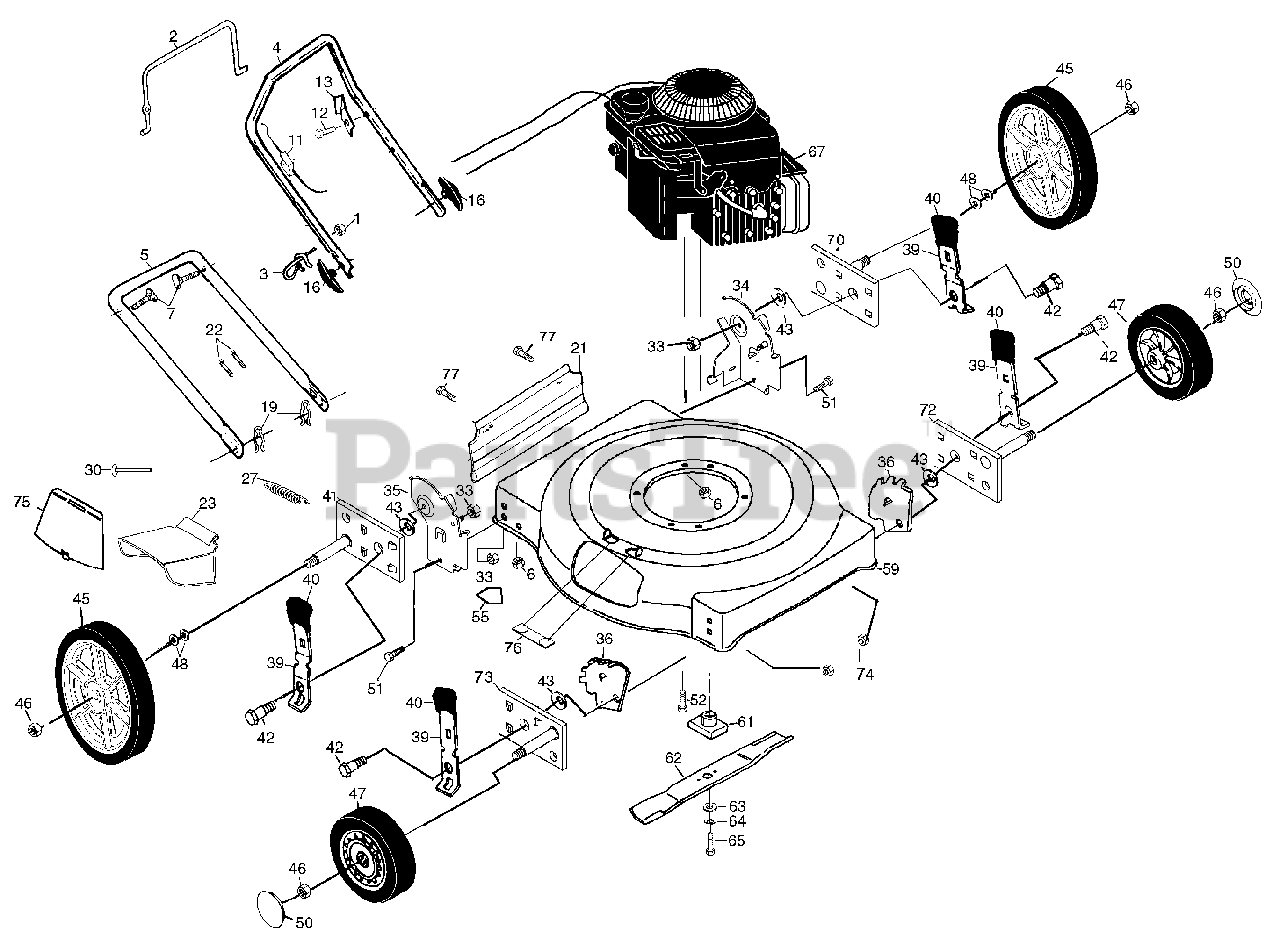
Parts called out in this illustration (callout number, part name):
1	Locknut 1/4-20
2	Control Bar
3	Rope Guide
5	Lower Handle
6	Locknut 1/4-20
7	Handle Bolt 5/16-18
11	Engine Zone Control Cable
12	Hex Washer Head Screw #10-24 x 1/2
13	Up-Stop Bracket
16	Handle Knob
19	Hairpin Cotter
21	Rear Deflector
22	Wire Tie
23	Discharge Guard
27	Torsion Spring
30	Hinge Rod
33	Locknut 5/16-18
34	Wheel Bracket Support (Left)
35	Wheel Bracket Support (Right)
36	Wheel Bracket Adjuster
39	Selector Spring
40	Selector Knob
41	Axle Arm Assembly (RR)
42	Shoulder Bolt
43	Washer
44	Shoulder Bolt
45	Wheel Assembly (Rear)
46	Locknut 1/16-18
47	Wheel Assembly (Front)
48	Washer
50	Hubcap
51	Hex Head Bolt 5/16-18 x 3/4
52	Hex Head Thread Rolling Screw 3/8-16 x 1
55	Danger Decal
59	Lawn Mower Housing
61	Blade Adapter
62	22" Blade
63	Hardened Washer
64	Helical Lockwasher 3/8
65	Screw Hex Head 3/8-24 x 1-3/8 (Grd. 8)
70	Axle Arm Assem.(LR)
72	Axle Arm Assm. ((LF)
73	Axle Arm Assm. (RF)
74	Nut
75	Plate. Mulcher
76	Clip. Closeout
77	Screw
77	Operator's Manual (English)
77	Operator's Manual (Spanish)
77	Replacement Parts Manual
77	Grass Catcher
